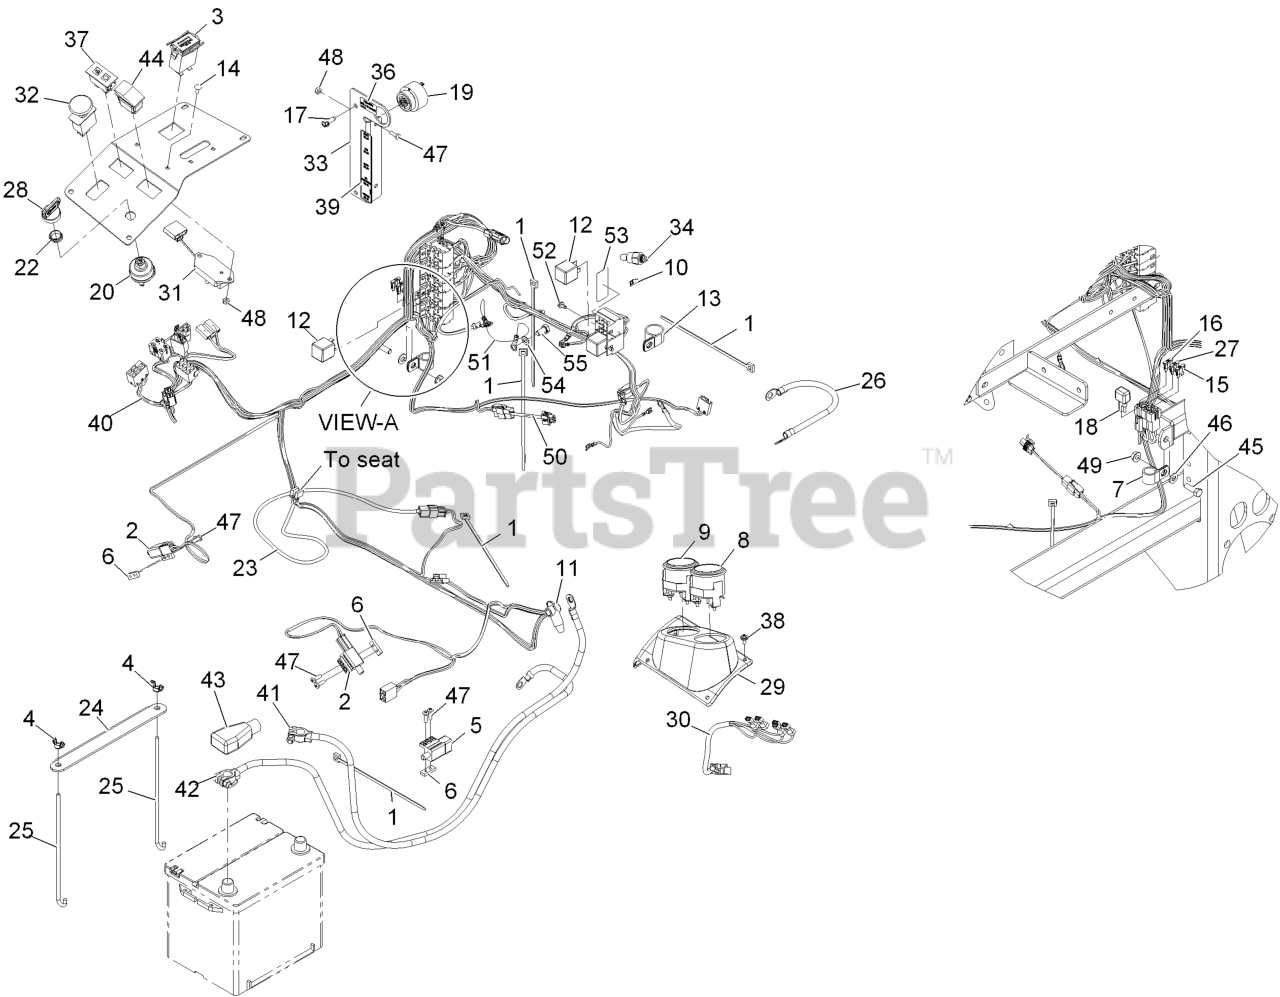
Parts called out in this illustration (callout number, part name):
1	TIE-PLASTIC
2	SWITCH-OPEN, NORMALLY
3	METER-HOUR
4	WINGNUT
6	PLATE-TAPPED
7	CLIP-LOOM
8	GAUGE-TEMPERATURE
9	GAUGE-VOLTMETER
11	INSULATOR-STARTER
13	CLIP-LOOM
14	BOLT-CARR
15	FUSE-BLADE TYPE, 20 AMP
16	FUSE-BLADE TYPE, 30 AMP
17	SCREW-HWHTF
19	ALARM-TONE, DUAL
22	NUT-SWITCH, IGNITION
23	HARNESS-WIRING, SEAT
24	HOLDDOWN-BATTERY
25	BOLT-HOLDDOWN
26	CABLE-ENGINE NEGATIVE
27	FUSE-40 AMP
28	KEY-IGNITION
29	BEZEL, GAGE XP LH TANK
30	HARNESS-GAUGE
31	MODULE-DELAY, SEAT
32	SWITCH-PTO, ON-ON
33	ASM,RELAY BRKT W/ DECALS
34	SENDER,TEMPERATURE
37	LAMP-WARNING
38	SCREW-PPH
39	DECAL,RELAY KUBOTA
40	HARNESS-WIRE
41	CABLE-BATTERY NEGATIVE
42	ASM,POSITIVE BATTERY CABL
43	INSULATOR-TERMINAL, BATTE
44	SWITCH-ROCKER
45	SCREW-HH
46	WASHER-PLAIN
47	SCREW-PPH
48	NUT-LOCK, NI
50	HARNESS-WIRE
51	GROUND WIRE ASM
52	SCREW-HWH
53	DECAL-RELAY DIESEL
54	WASHER-LOCK
55	SCREW-HH
